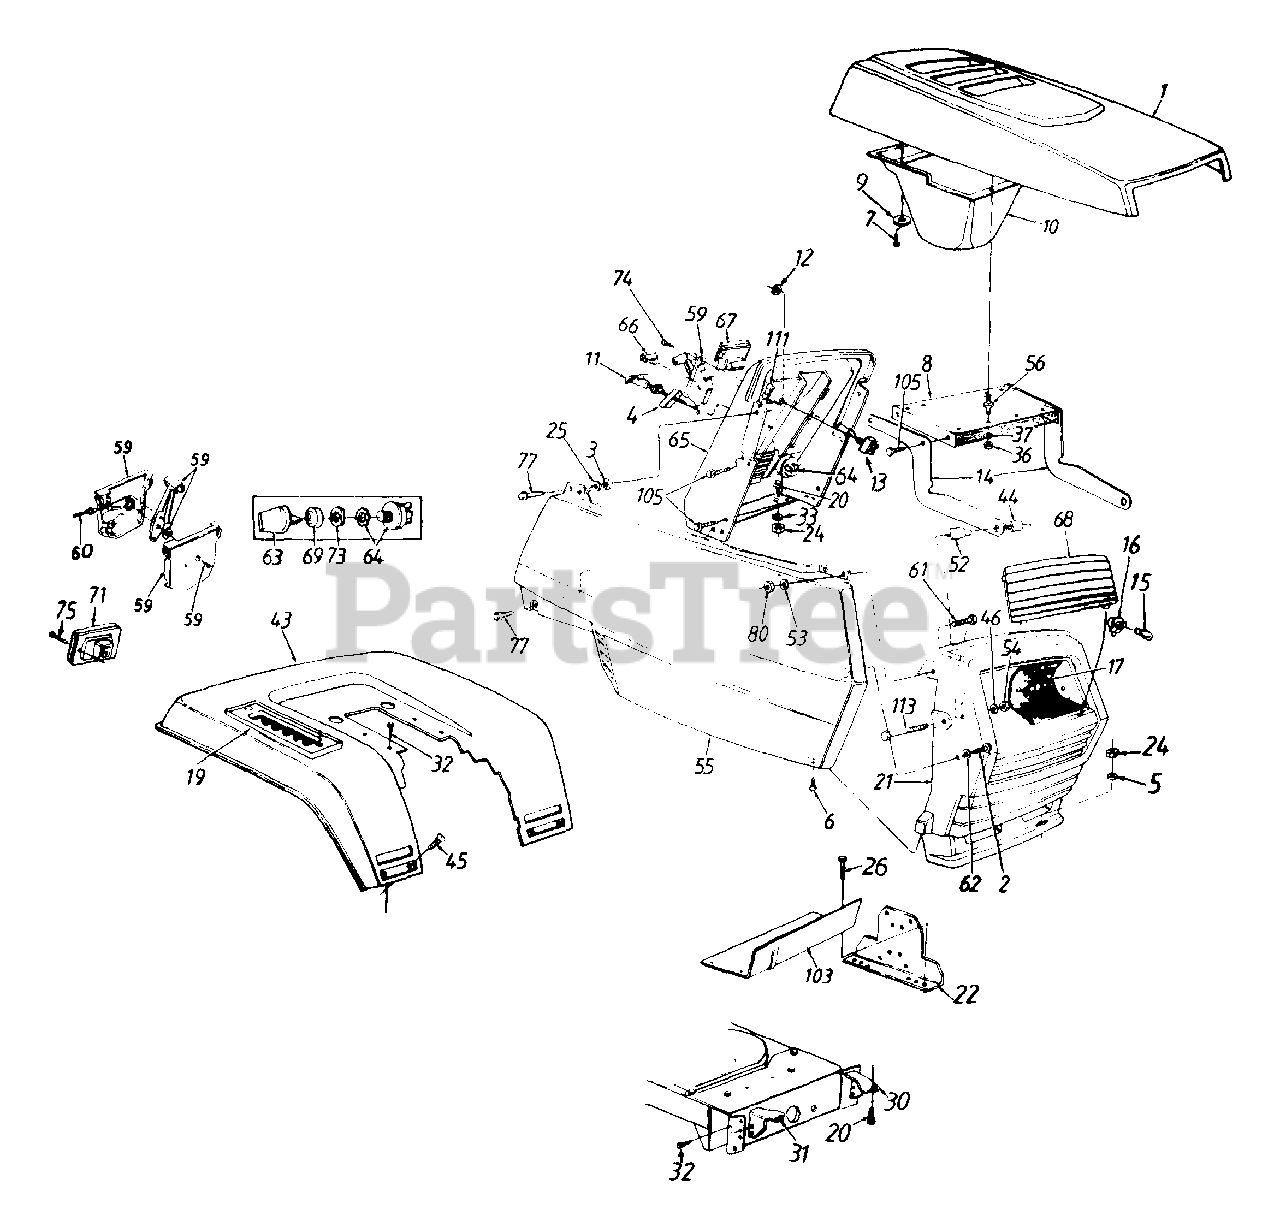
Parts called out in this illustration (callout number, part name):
1	Hood
2	Hex Wash. B-Tap Scr. 1/4 x .62" Lg.
3	Bolt Retainer 1/4" I.D.
4	Retainer Clip
5	Fl-Wash. .34" I.D. x 1"
6	Truss Mach. B-Tap Scr. #10 x .5" Lg.
7	Hex Wash. Hd. AB-Tap Scr. #8 x .5" Lg.
10	Air Plentum
11	Choke Control
12	Hex Nut 1/2-27 Thd.
13	Toggle Switch
14	Hood Hinge
15	Lamp
16	Twist Lock - Lamp Socket
17	Reflector - Headlight
21	Grille
25	Fl-Wash. 1/4" I.D. x .93" O.D.
26	Hex Wash. Hd. B-Tap Scr. 5/16-18 x .5" Lg.
30	Grille Mount Brkt. - L.H.
31	Grille Mount Brkt. - R.H.
32	Hex Wash. Hd. AB-Tap Scr. 5/16 x .75" Lg.
33	Bell-Wash. .345" I.D. x .88"
36	Hex Nut 1/4-20 Thd.
37	Bell-Wash. .265" I.D. x .75"
45	Carriage Bolt 1/4-20 x .50" Lg
46	Fl-Wash. .328" I.D. x .68" O.D.
52	Shld. Spacer .33" I.D.
53	Fl-Wash. .281" I.D. x .5" O.D.
54	Hex Cent. L-Nut 5/16-18 Thd.
55	Side Cover - R.H.
56	Double Ended Stud 1/4-20 Thd.
59	Throttle Control Box Ass'y.
60	Throttle Control Wire 35" Lg.
61	Hex Bolt 1/4-20 x .62" Lg.
62	Fl-Wash. .281" I.D. x .73" O.D.
64	Ignition Switch
65	Dash Panel
66	Light Switch
67	Ammeter
68	Lens
69	Ignition Switch Cap
71	Taillight
73	Ignition Switch Nut
74	Truss Mach. AB-Tap Scr. #10 x .5" Lg.
75	Truss Hd. AB-Tap Scr. #6 x .62" Lg.
77	Hex Wash. Hd. Tap Scr. 1/4 x .75" Lg.
80	Hex L-Nut 1/4-20 Thd.
111	Speed Nut 1/4-20 Thd.
113	Hex Bolt 5/16-18 x 2.75"
17324B-0648	Fender - TECH GRAY (0648)
